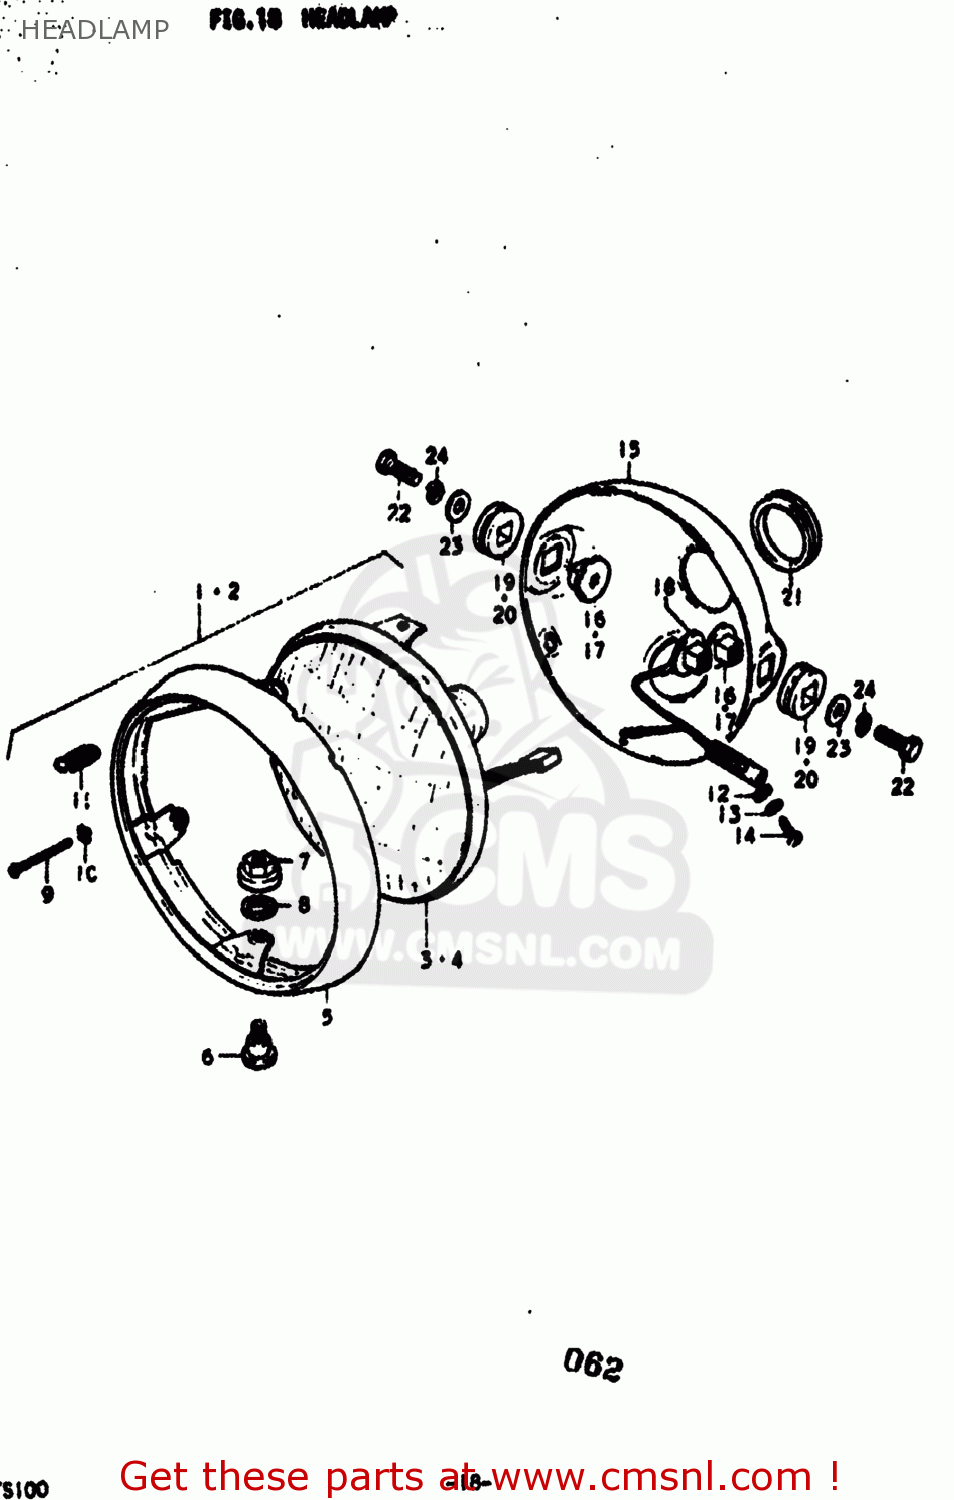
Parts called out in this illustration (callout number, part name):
1	HEADLAMP ASSEMBLY
2	LAMP ASSEMBLY,HEAD
3	LAMP UNIT
4	UNIT,HEADLAMP
5	RIM,HEADLAMP
6	SCREW
7	NUT,ADJUSTING
8	SPACER,HEADLAMP UNIT
9	SCREW,HEADLAMP ADJUST
10	NUT,HEADLAMP ADJUSTER
11	SPRING,HEADLAMP ADJUST
12	WASHER
13	LOCK WASHER
14	SCREW
15	HOUSING COMP,HEADLAMP
16	SPACER, HOUSING RH
17	SPACER,HEADLAMP HOUSING
18	SPACER,HEADLAMP HOUSING
19	CUSHION,HEADLAMP HOUSING
20	CUSHION,HEADLAMP HOUSING
21	GROMMET,HEADLAMP HOUSING
22	BOLT
23	WASHER
24	LOCK WASHER
